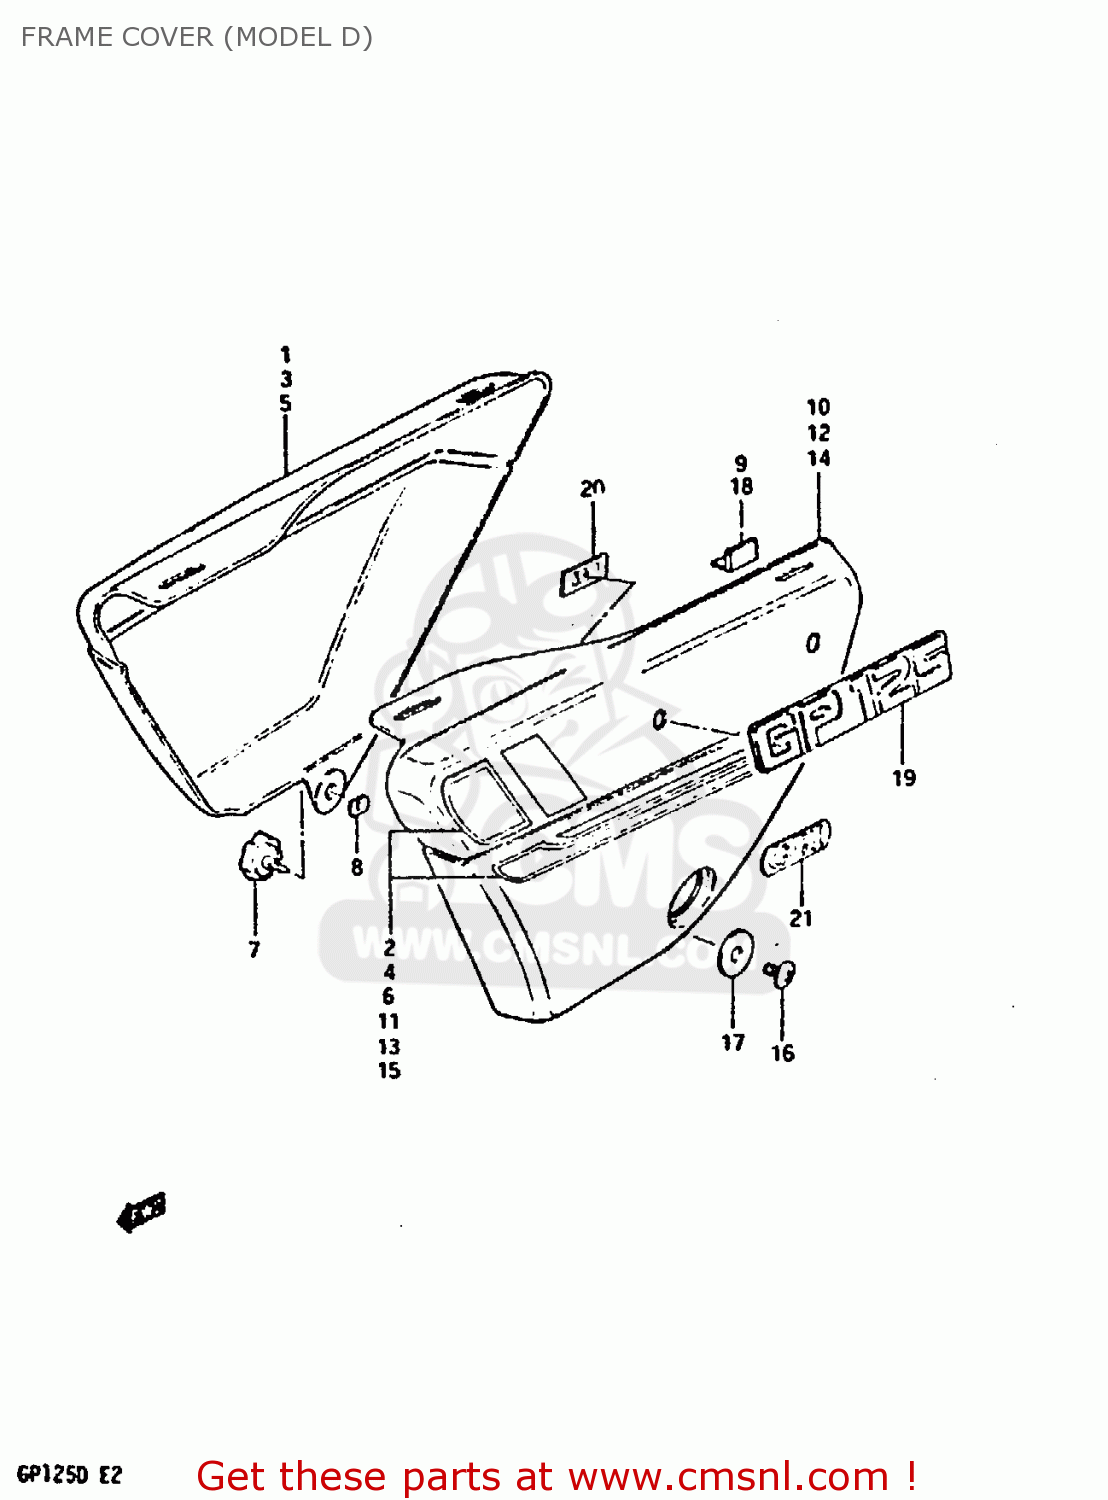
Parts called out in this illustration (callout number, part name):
1	COVER, FRAME RH
2	TAPE, RH
3	COVER, FRAME RH
4	TAPE, RH
5	COVER, FRAME RH (BLACK)
6	TAPE, RH
7	KNOB,FRAME COVER,R
8	NUT
9	CUSHION,FRAME COVER
10	COVER, FRAME LH
11	TAPE, LH
12	COVER, FRAME LH
13	TAPE, LH
14	COVER, FRAME LH (BLACK)
15	TAPE, LH
16	SCREW
17	WASHER
18	CUSHION,FRAME COVER
19	EMBLEM
20	NUT
21	EMBLEM,CCIS
